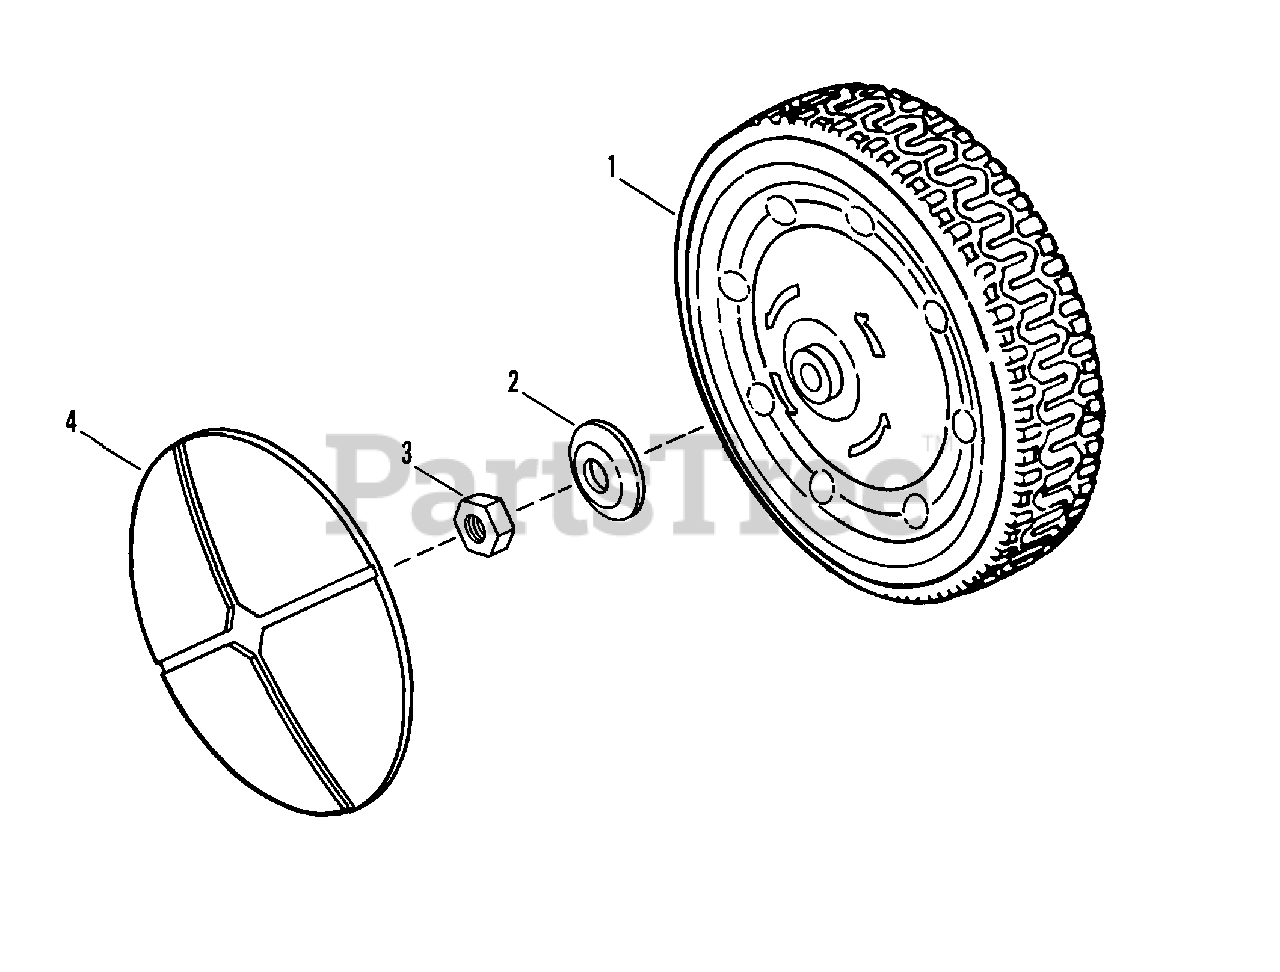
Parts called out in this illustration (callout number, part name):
1	WHEEL, 9 x 2.00, Steel
2	HUB-CAP
3	NUT, 7/16-20 Hex (Thin)
4	WHEEL COVER, 9"
